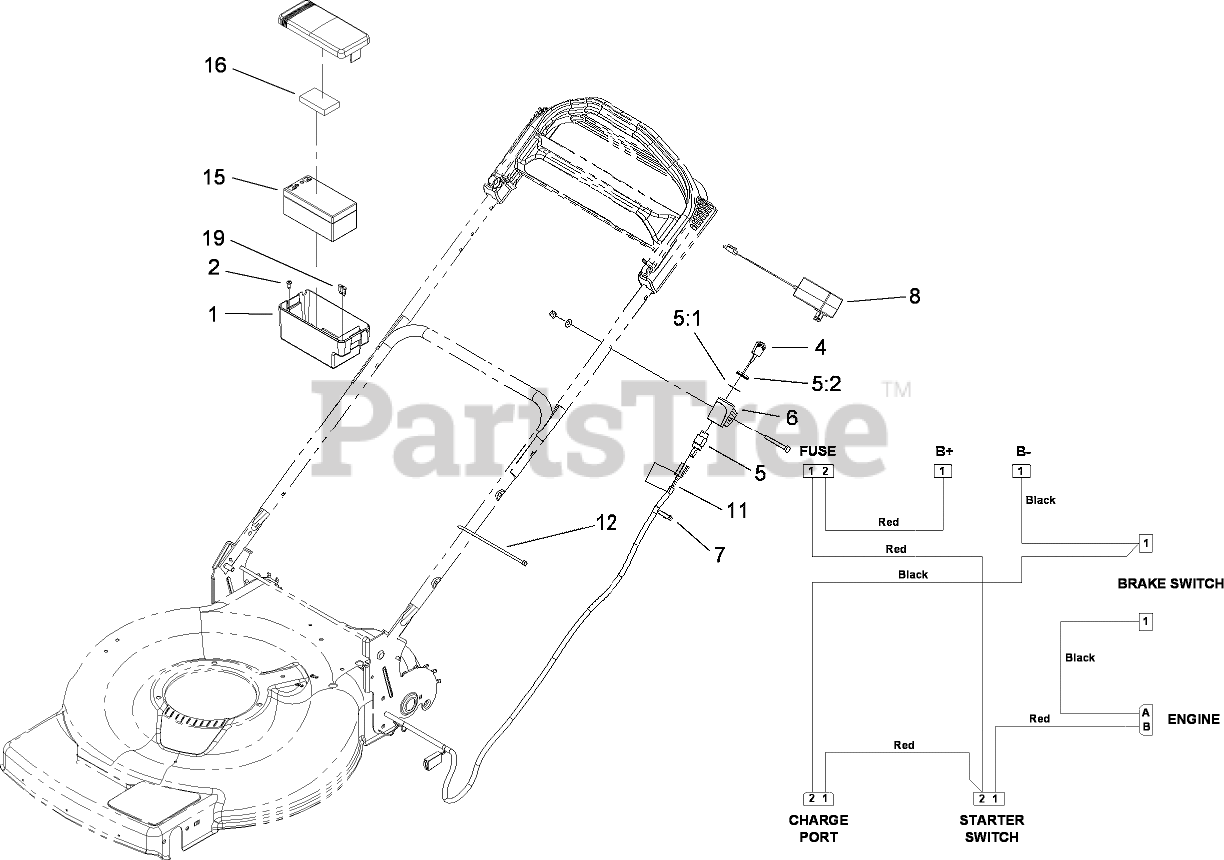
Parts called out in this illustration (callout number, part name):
1	BATTERY BOX ASM
2	SCREW-FORMING, THREAD
5	STARTER SWITCH ASM
5:1	WASHER-TOOTH, INTERNAL
5:2	NUT-HH
6	MOUNT-SWITCH
7	HARNESS-WIRE
8	CHARGER-12 VOLT
11	DECAL-WARNING
12	TIE-CABLE
15	BATTERY-WET
16	FOAM-BATTERY, TOP
19	FUSE-40 AMP
